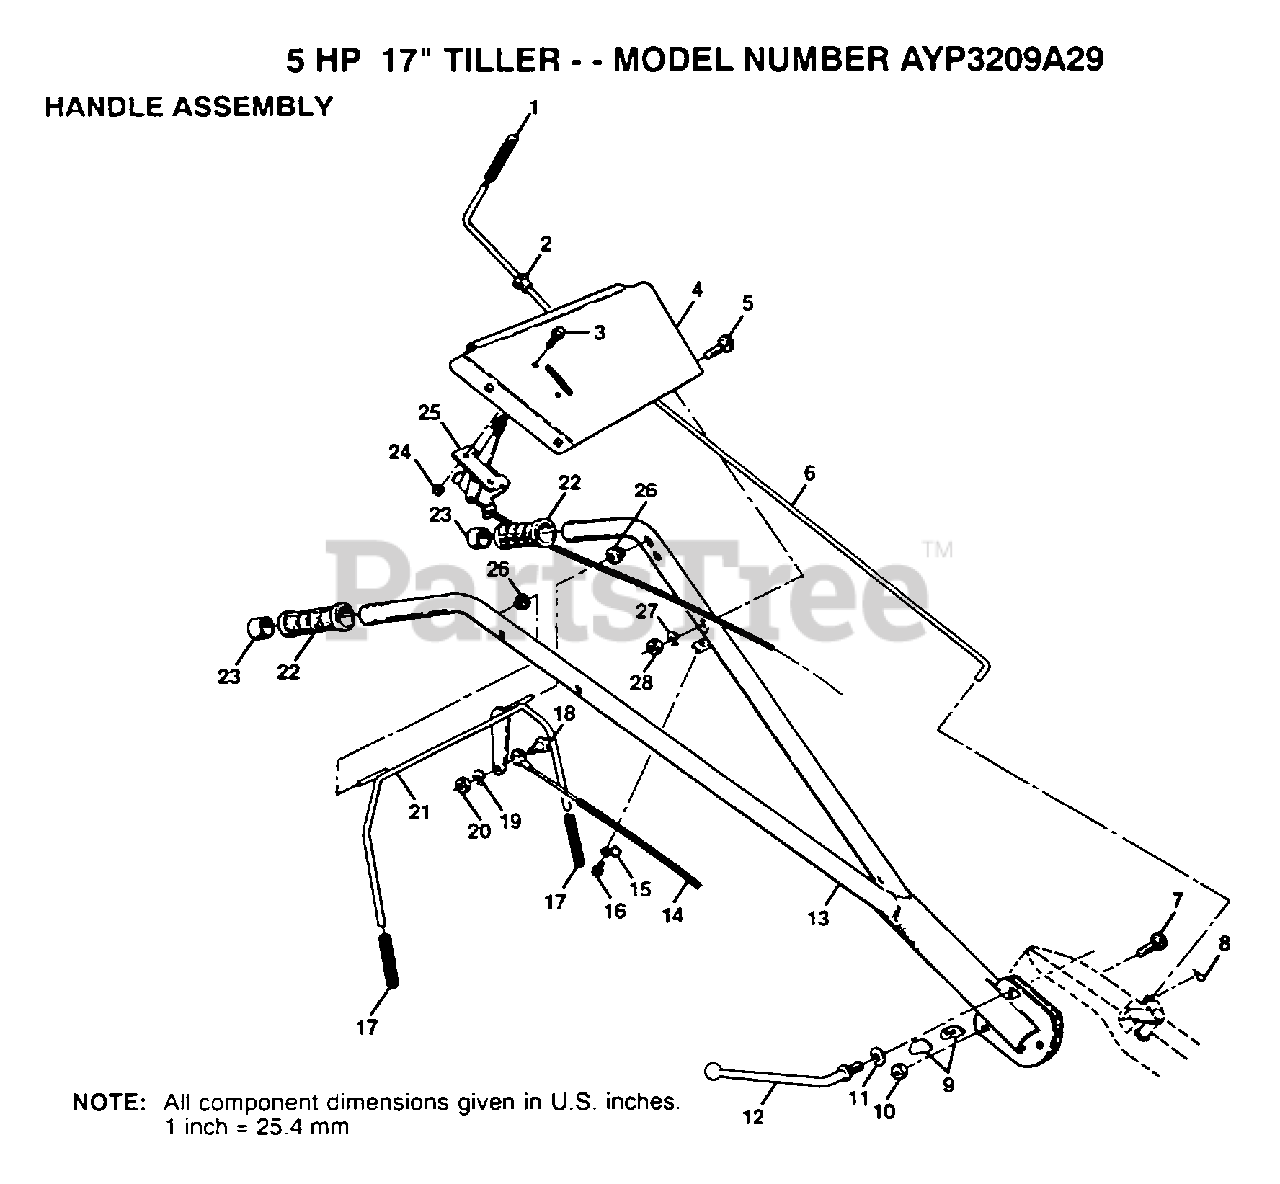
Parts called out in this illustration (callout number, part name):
1	GRIP TI
2	BUSHING
3	SCREW
4	HANDLE BRACKET
5	BOLT CARRIAGE CRT
6	ROD SHIFT CRT
7	BOLT D
8	RETAINER M
9	LOCK CRT
10	LOCKNUT
11	WASHER CRT
12	LEVER LOCK CRT
14	CABLE.CLUTCH.CRT
15	CONDIUT CLIP T
17	GRIP BAR CRT
18	SHOULDER BOLT ST
19	LOCKWASHER
21	HANDLE BAR CRT
23	CAP CRT
25	"CONT,THROTTLE"
27	LOCKWASHER
